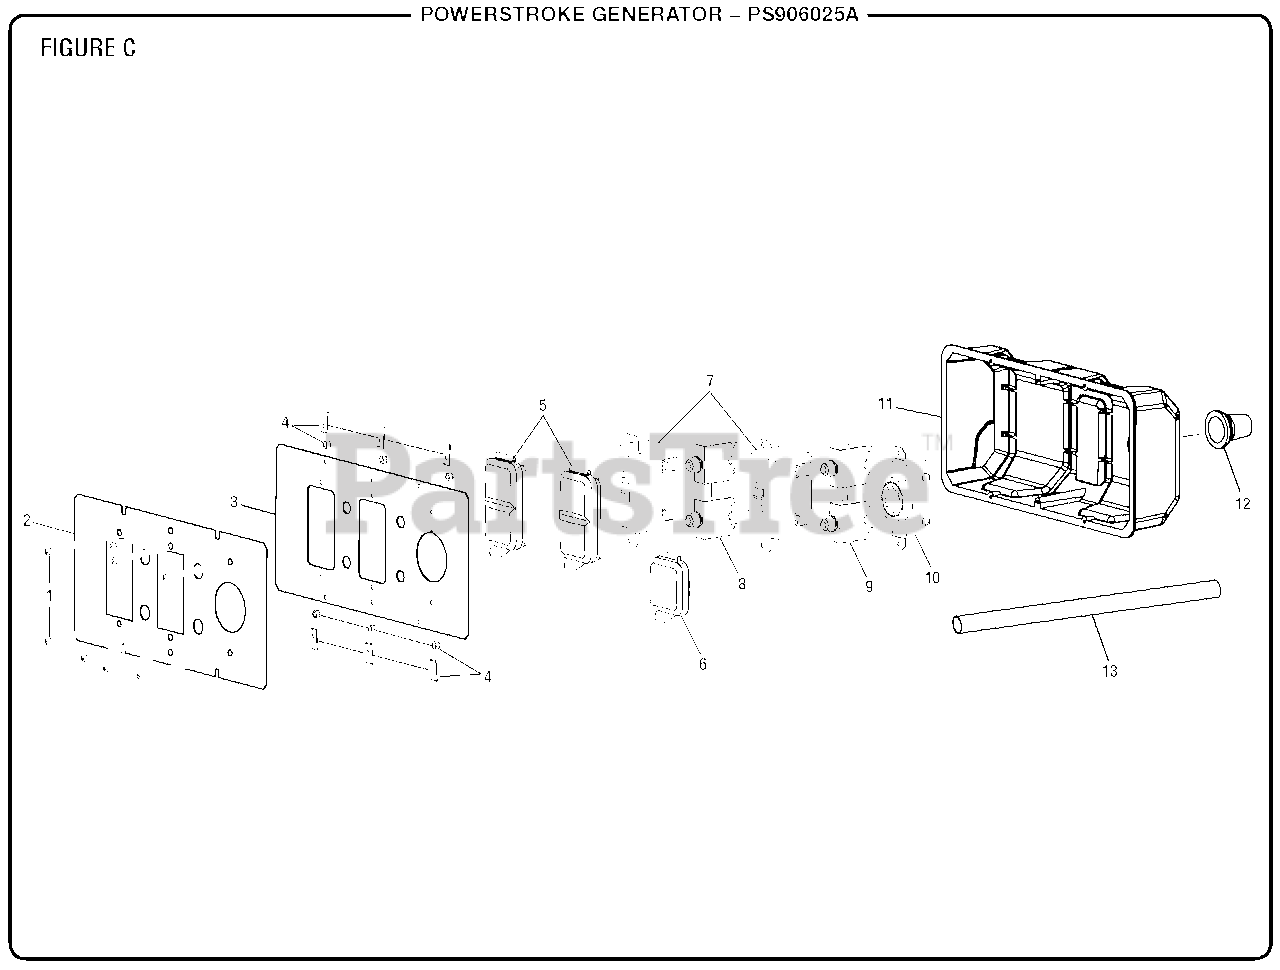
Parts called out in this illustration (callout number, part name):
1	Screw (6-20 x 3/8 in.)
2	Label (Power Outlet)
3	Front Panel
4	U-Clip Nut
5	Outlet Cover (120 Volt)
6	Outlet Cover (240 Volt)
7	Duplex Receptacle (120 Volt)
8	Circuit Breaker, 20 Amp
9	Circuit Breaker, 25 Amp
10	Twist Lock Receptacle (240 Volt)
11	Control Box (Back Panel)
12	Rubber Boot
13	Wire Sleeve
